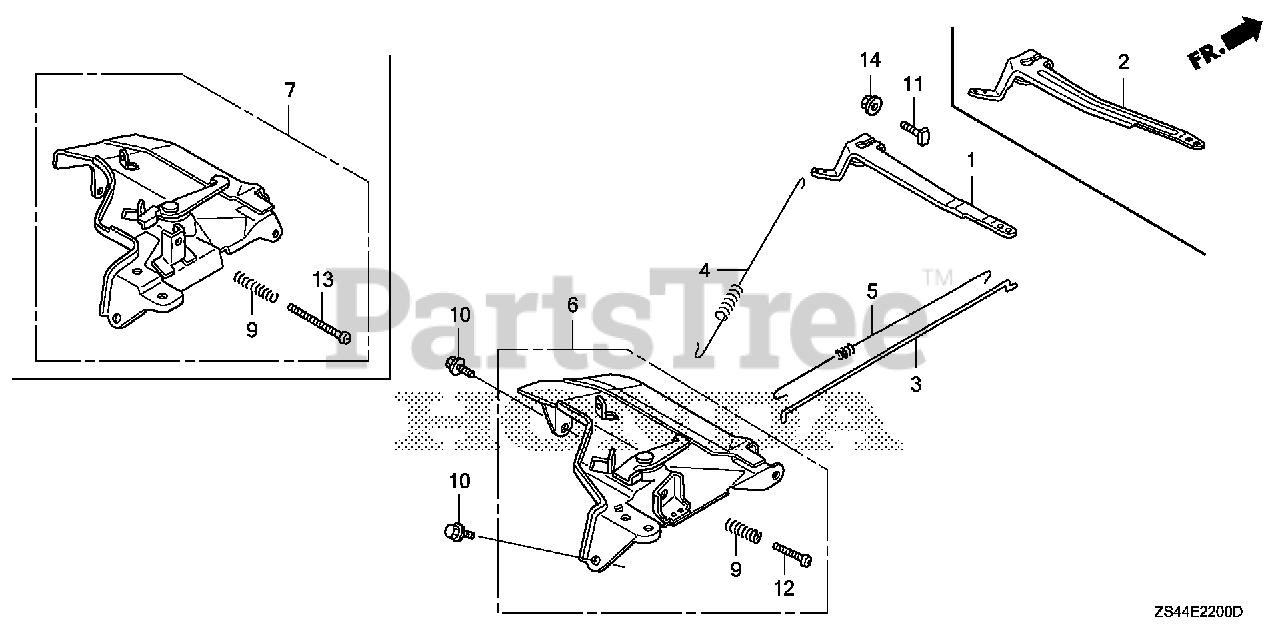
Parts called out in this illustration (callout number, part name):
1	ARM, GOVERNOR
3	ROD, GOVERNOR
4	SPRING, GOVERNOR (L=145.0MM) (WIRE DIAMETER 1.0MM)
5	SPRING, THROTTLE RETURN
6	CONTROL ASSY.
9	SPRING, CONTROL ADJUSTING
10	BOLT, FLANGE (6X12) (CT200)
11	BOLT, GOVERNOR ARM
12	SCREW, PAN (5X35)
14	NUT, FLANGE (6MM)
